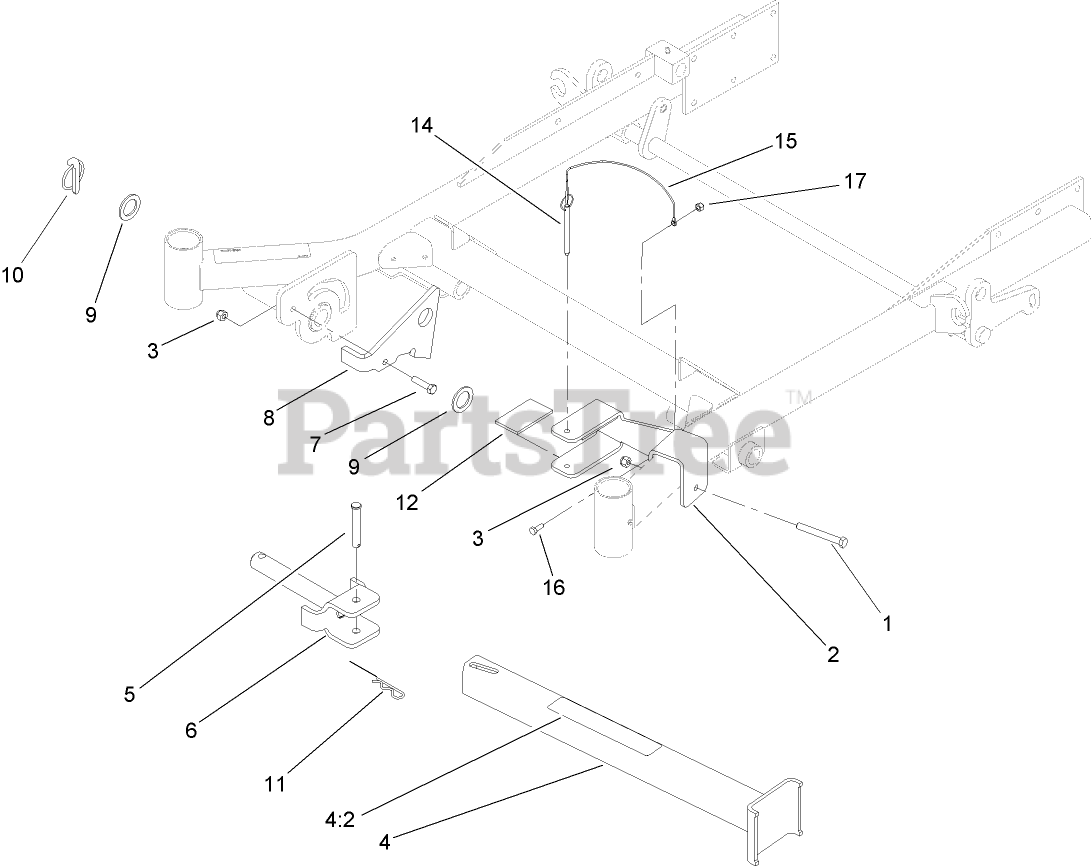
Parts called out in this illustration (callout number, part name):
1	SCREW-HH
2	BRACKET-CRADLE
3	NUT-LOCK, NI
4	Leg ASM
4:2	DECAL-Z STAND
5	PIN-CLEVIS
6	PIN-PIVOT
7	SCREW-HH
8	BRACKET-LATCH
9	WASHER-THRUST
10	PIN-LYNCH
11	PIN-HAIR
12	Cushion-Rubber
14	PIN-HITCH, COTTERLESS
15	LANYARD-NYLON
16	SCREW-HH
17	NUT-LOCK, NI
